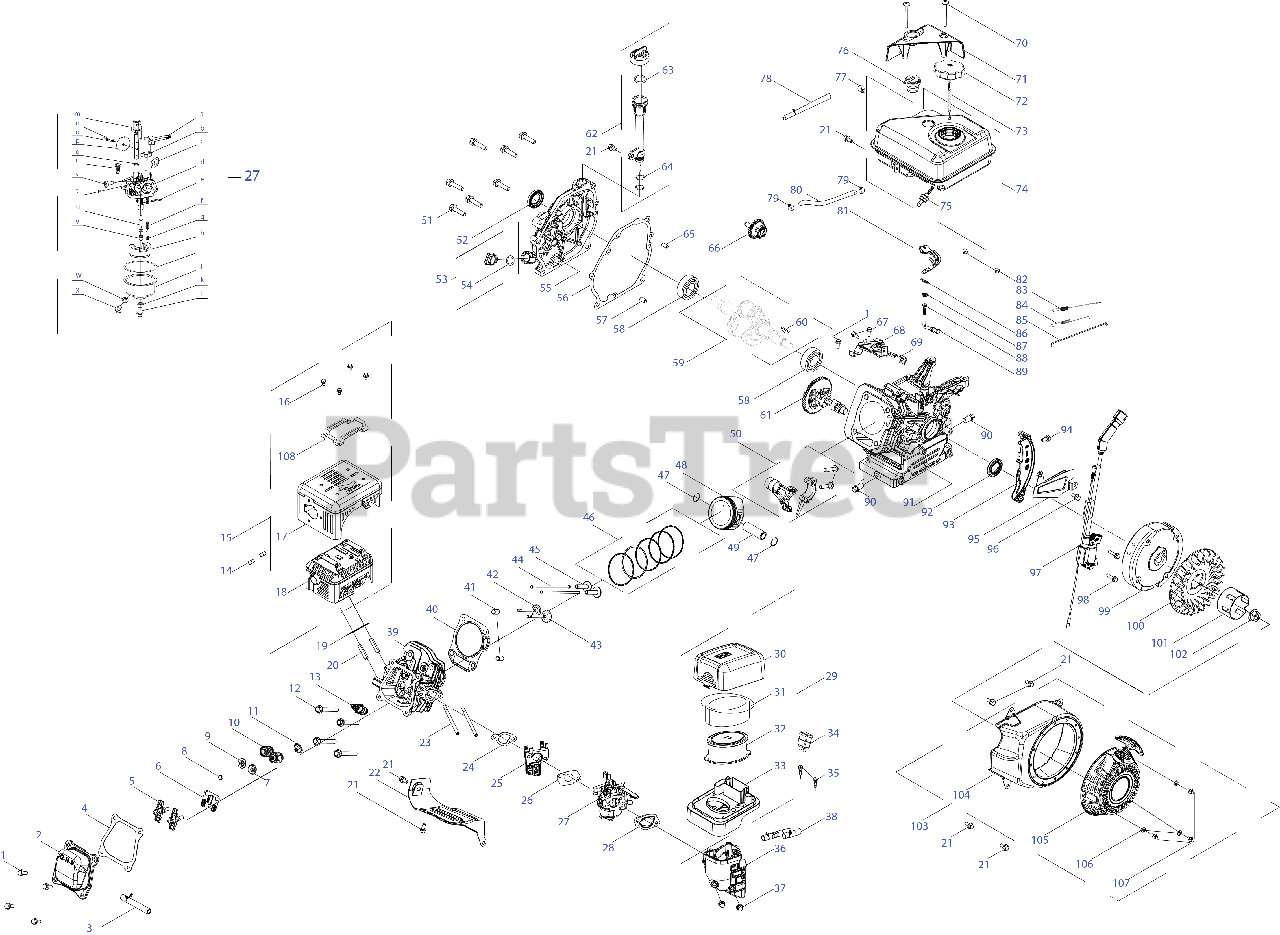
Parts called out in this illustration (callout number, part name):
1	BOLT M6 x 16
2	VALVE COVER
3	BREATHER HOSE
4	VALVE COVER GASKET
5	ROCKER ARM ASSEMBLY
6	ROCKER ARM BASE
7	INTAKE VALVE SPRING RETAINER
8	EXHAUST VALVE ADJUSTER
9	EXHAUST VALVE SPRING RETAINER
10	VALVE SPRING
11	INTAKE VALVE SEAL
12	BOLT-M8-1.25 x 60 GR10.9
13	SPARK PLUG
15	MUFFLER ASSEMBLY
16	BOLT M5-.8 x 8 CL10.9
17	MUFFLER GUARD
18	MUFFLER BODY
19	MUFFLER GASKET
20	STUD M8 x 36
21	BOLT M6-1 x 12 GR8.8
22	AIR SHIELD
23	STUD M6-1 x 110 GR8.8
24	CARBURETOR INSULATOR GASKET
25	CARBURETOR INSULATOR
26	CARBURETOR GASKET
27	CARBURETOR ASSEMBLY
28	CARBURETOR GASKET PLATE
29	AIR CLEANER ASSEMBLY
30	AIR FILTER COVER
31	AIR FILTER ELEMENT
32	AIR CLEANER WITH PRE-FILTER
33	SILENCER PLATE
34	CARBON CANISTER
35	SCREW M4x20
36	AIR CLEANER HOUSING
38	PRIMER HOSE
39	CYLINDER HEAD
40	CYLINDER HEAD GASKET
42	EXHAUST VALVE
43	INTAKE VALVE
44	PUSH ROD
46	PISTON RING 4PC SET
47	PISTON PIN SNAP RING
49	PISTON PIN
50	CONNECTING ROD ASSEMBLY
51	BOLT M8-1.25 x 32 GR5.8
52	OIL SEAL 25 x 41.25 x 6
54	O-RING 15.8 x 2.5
55	CRANKCASE COVER
56	CRANKCASE COVER GASKET
57	DOWEL PIN
59	CRANKSHAFT
60	FLYWHEEL KEY
61	CAMSHAFT ASSEMBLY
62	DIPSTICK ASSEMBLY
63	DIPSTICK O-RING
64	OIL FILL TUBE O-RING
65	DOWEL PIN
66	GOVERNOR GEAR/SHAFT ASSEMBLY
67	BOLT M6-1 x 12 GR8.8
68	GOVENOR GEAR BRACKET
69	THROTTLE KNOB
70	BOLT M6-1 x 67
71	ENGINE/DIPSTICK COVER
72	FUEL CAP BLACK
75	FUEL INLET NIPPLE
76	ROLLOVER VALVE
77	FUEL HOSE CLAMP
78	HOSE ASSEMBLY
79	HOSE CLAMP
80	FUEL HOSE (6.3x12.5x123MM)
81	GOVERNOR LEVER
83	GOVERNOR SPRING
84	THROTTLE RETURN SPRING
85	GOVERNOR ROD
86	COTTER PIN
87	GOVERNOR SEAL
89	GOVERNOR SHAFT
90	DRAIN BOLT M10 x 1.25
92	OIL SEAL-25 x 41.25 x 6
93	LOWER SHIELD
94	SCREW M6-1 x 20 CL5.8
95	AIR FLOW SHIELD
96	BOLT M6-1 x 10 GR8.8
97	IGNITION COIL
98	BOLT M6-1 x 25 GR8.8
100	COOLING FAN
101	STARTER CUP
102	FLYWHEEL NUT
103	RECOIL STARTER
104	BLOWER HOUSING
105	RECOIL STARTER
106	RECOIL FLAT WASHER
107	BOLT M6 x 10
108	MUFFLER GUARD
